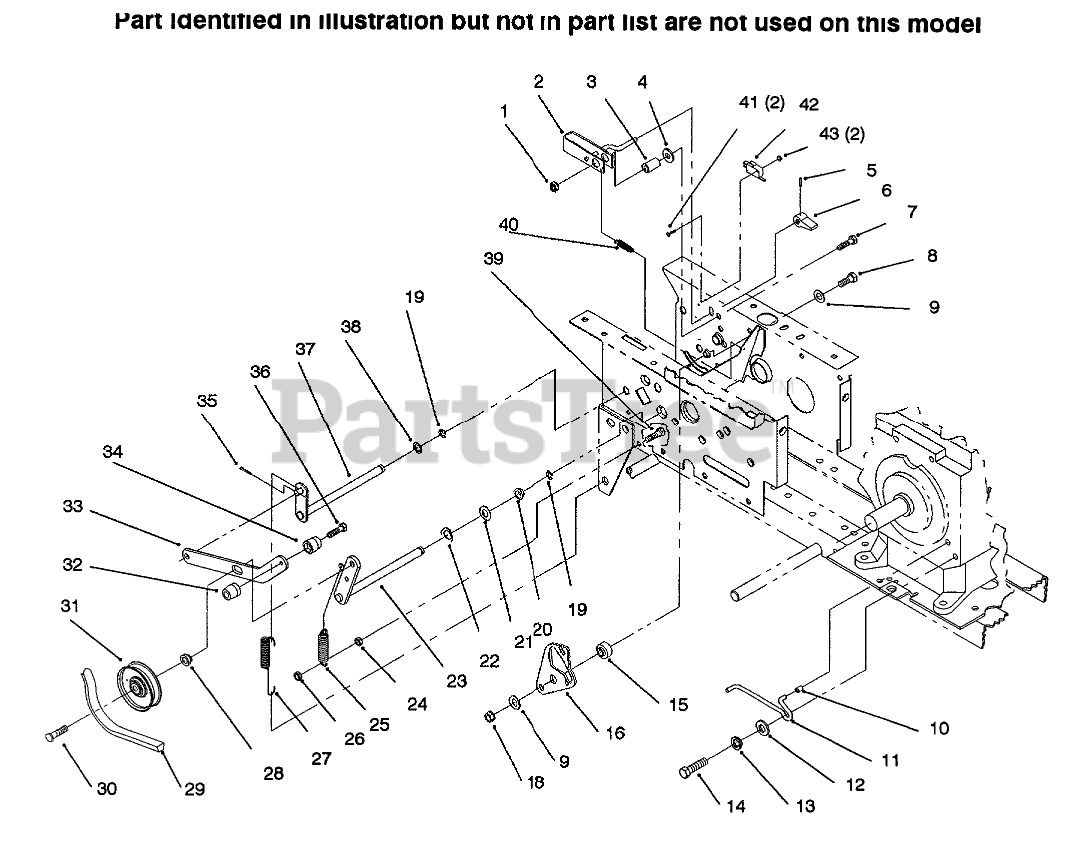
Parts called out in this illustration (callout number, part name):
1	LOCKNUT-FLANGE
2	Lever-Parking Brake
3	SPACER
4	WASHER-SPACER
5	PIN-SPIROL 3/32X5/8
6	KNOB-PARKING BRAKE
7	SCREW-HH
8	SCREW-HH
9	WASHER-FLAT
15	Spacer
16	Cam Plate
18	NUT-LOCK, NI
19	RING-RETAINING, EXTERNAL
20	BUSHING-FLANGED
21	SHIM-WASHER
22	CURVED-SPRING WASHER
23	WLDMT-IDLER ARM
24	NUT-HEX
25	SPRING-EXTENSION
26	NUT-LOCK
29	BELT-V
30	SCREW-HH
31	PULLEY-IDLER
39	SCREW-HH
40	EXTENSION-SPRING
41	Screw
42	SWITCH
43	NUT-HEX
